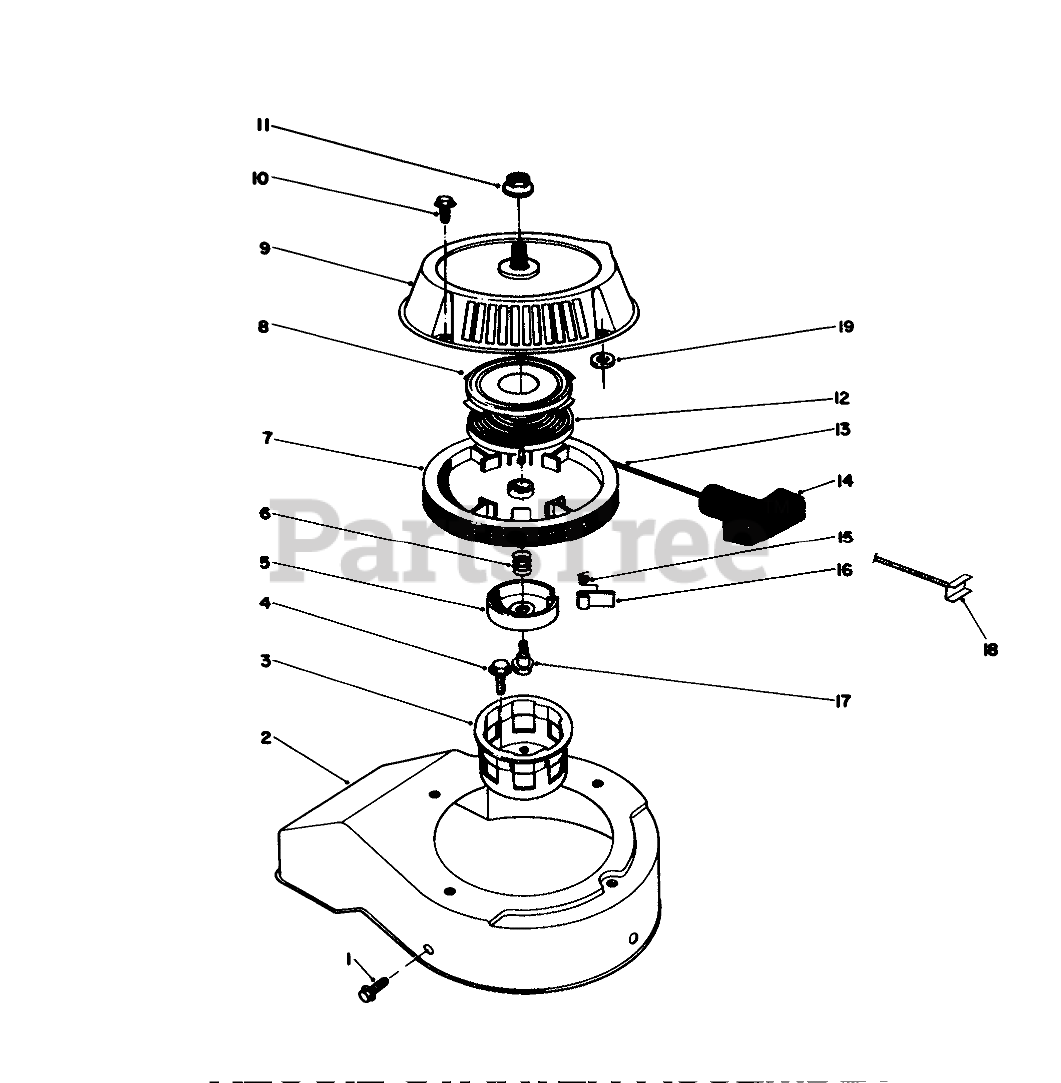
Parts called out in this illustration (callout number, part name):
2	BLOWER SHROUD
3	CUP - STARTER
4	WASHER-FLAT HD, TREATED
5	RETAINER
6	SPRING
8	Retainer-Recoil Spring
9	RECOIL CASE
10	MOUNTING SCREW
11	NUT (F/W & PPP)
12	Spring-Recoil
13	ROPE-STARTER
14	HANDLE-RECOIL
15	SPRING
18	Insert Handle
19	SPACER-PLATE, PIVOT
